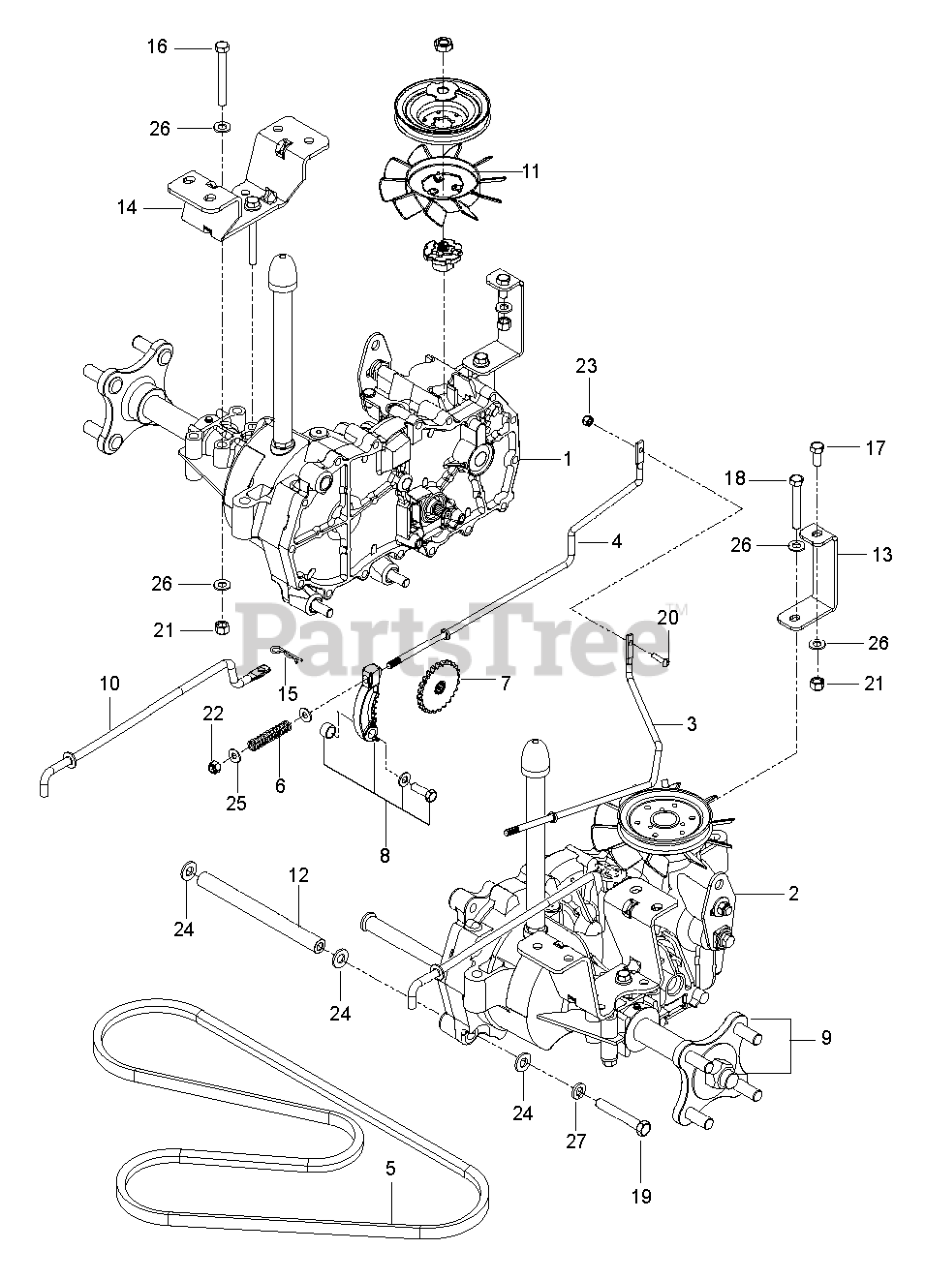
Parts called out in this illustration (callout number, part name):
1	HG_EZT, LT
2	HG_EZT, RT
3	LINKAGE.BRAKE.LT
4	LINKAGE, BRAKE RT
5	BELT, HYDRO PUMP
7	HG_DISC COG BRAKE 51635
8	HG_KIT BRAKE ARM (EZT)
9	HG_KIT, HYDRO-GEAR HUB
10	LINKAGE, BYPASS, EZT
11	HG_HYDRO FAN 51365
12	SPACER TUBE, EZT
13	SUPPORT.FRONT.TRANS.PNTX431
14	BRACKET.EZT.MOUNT.REAR.PNTX431
15	HAIRPIN #2
17	HCS 5/16C X 3/4
18	BOLT.FIN HEX 5/16-18UNC X2 1/4
19	HCS 3/8C X 2 1/2
20	SCR #10-24 X 3/4
21	NUT.71038.31-18.HEX.NYLOCK
22	NUT.1/4-20.HEX.NYLOC.ZD
23	NUT 10-24 NYLOC
24	WASHER
26	WASHER
27	LOCKWASHER
